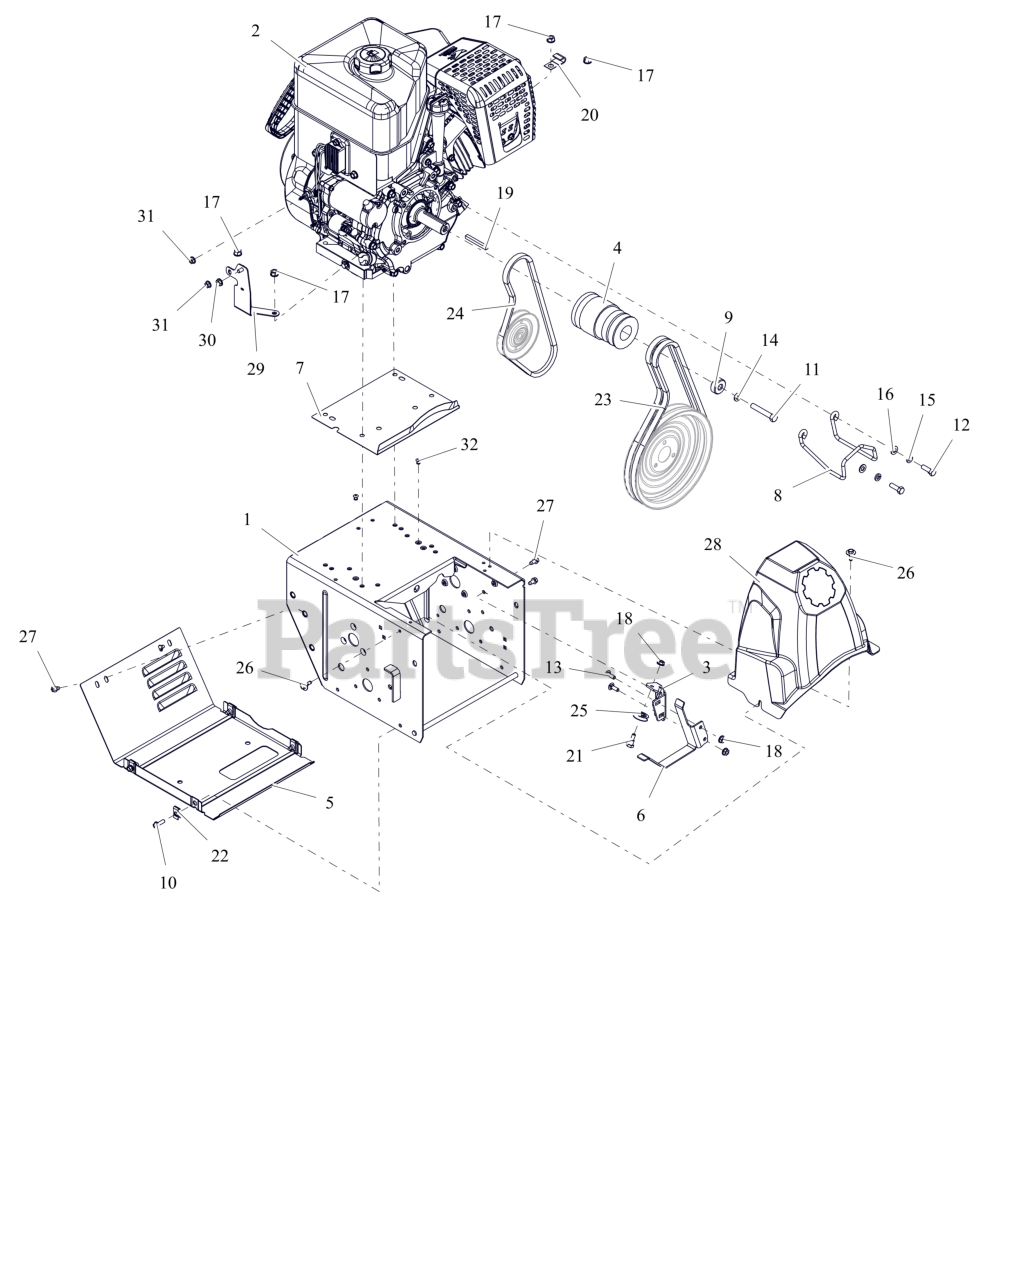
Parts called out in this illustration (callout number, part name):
1	FRAME, MAIN - PRO (WELDMENT)
2	ENGINE, EFI 420 GEN 3 12V
3	BRACKET, CLUTCH CABLE
4	SHEAVE, COMBO HYDRO TRACK 4L
5	COVER, BOTTOM - VENTILATED
6	FINGER, BELT - FLAT
7	BAFFLE, WATER - LARGE BLOCK
8	FINGER, BELT
9	BSHG, SPCR .406 X 1.250 X .500
10	BLT, HWH .25-20X.75 G5 ZCC
11	BLT, HEX .38-24X2.25 G5 ZCC
12	BLT, HEX 0.3125-24X1 G5 ZCC
13	BLT, RHSN .25-20X.750 G5 ZCC
14	WSHR,LK-REG .375X.094 ZCC
15	WSHR, LK-HVY .312X.097 ZCC
16	WSHR,FLT .344X.688X.065 ZCC
17	NUT,LK-CTR-FLG .31-18 GF ZCC
18	NUT-LK-TOP-FLG .250-20 GF ZCC
19	KEY .25X.25X2.25
20	J-CLAMP
21	BOLT, SHLDR -.375 X .375 X .25-20
22	NUT-RTNR .25-20X.56
23	V-BELT, HA-RAW EDGE (SET)
24	V-BELT, 4L-WRAPPED
25	PULLEY, CABLE
26	SCR-TAP .25-20X.5 CAPTIVE
27	SCR-TAP .25-20X.50 HWH ZCC
28	COVER, BELT
29	WLDMT- LG BLOCK FUSE MOUNT
30	NUT-LK-CTR-FLG .25-20 ZC120
31	NUT- CTRLK-FLG M6-1.0 G8.8 ZCC
32	RVT, POP .1875 ZCC
